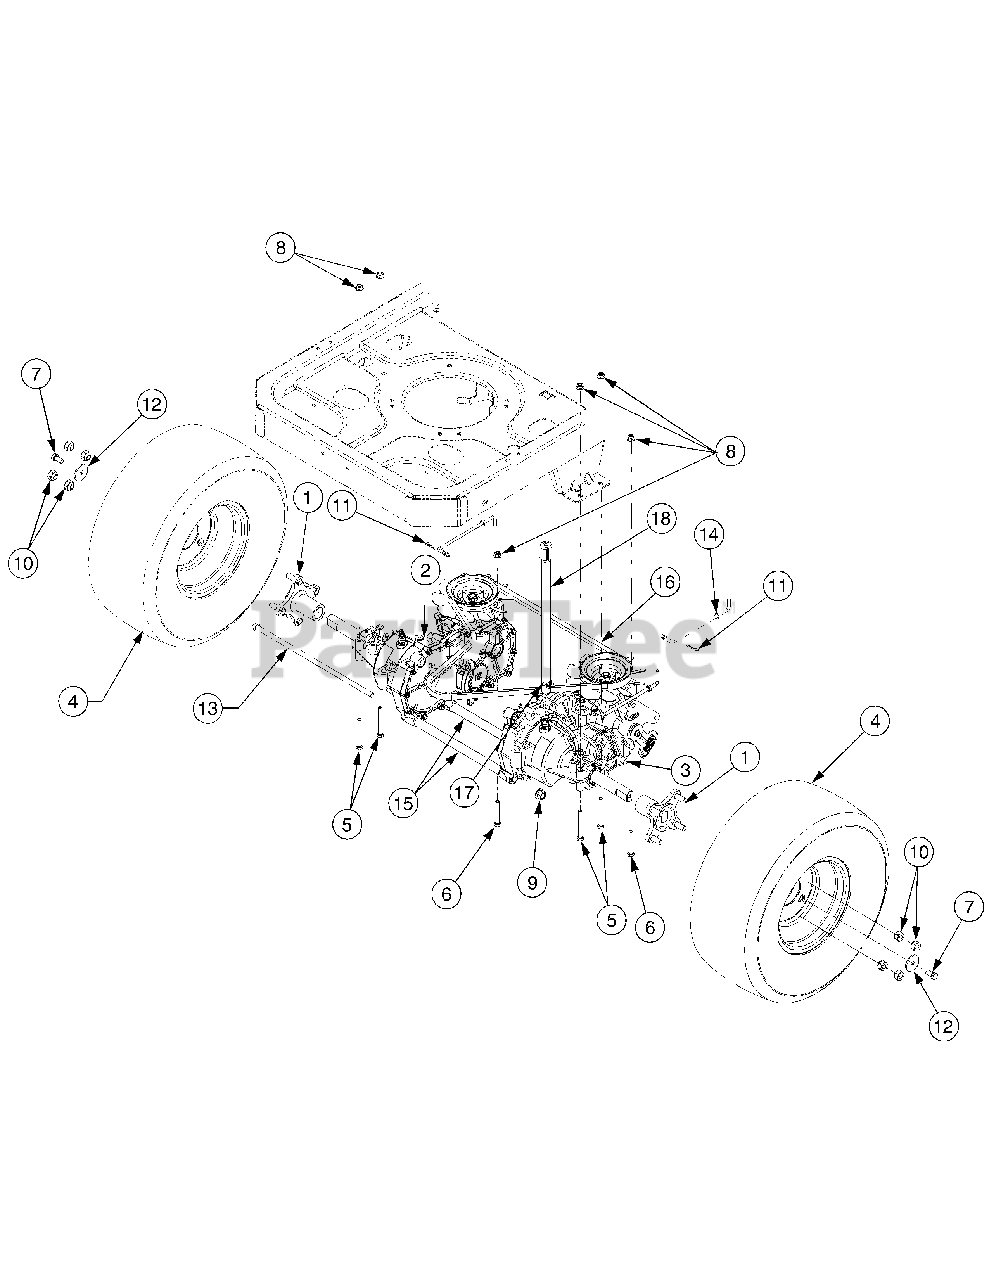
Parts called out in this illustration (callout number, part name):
1	Wheel Hub
2	Transmission Ass'y, LH
3	Transmission Ass'y, RH
4	Complete Wheel 18 x 9.8-8
4	Tire Only Carlisle
4	Tire Only Deli
5	Hex Screw 5/16-18 x 2.75
6	Hex Bolt 5/16-18 x 2.25
7	Hex Cap Lock Screw. 3/8-16 x .75 Gr. 5
8	Flange Locknut 5/16-18 Gr. F, Nylon
9	Flange Lock Nut, 7/16-20
10	Lub Nut, 7/16-14
11	Bow Tie Cotter Pin
12	Flat Washer .39 ID x 1.5 OD x .135
13	Rod, .405 x 14.0
14	Rod, Bypass
15	Tube, .45 x .69 x 10.2
16	V-Belt, Type A Sec x 57.7
